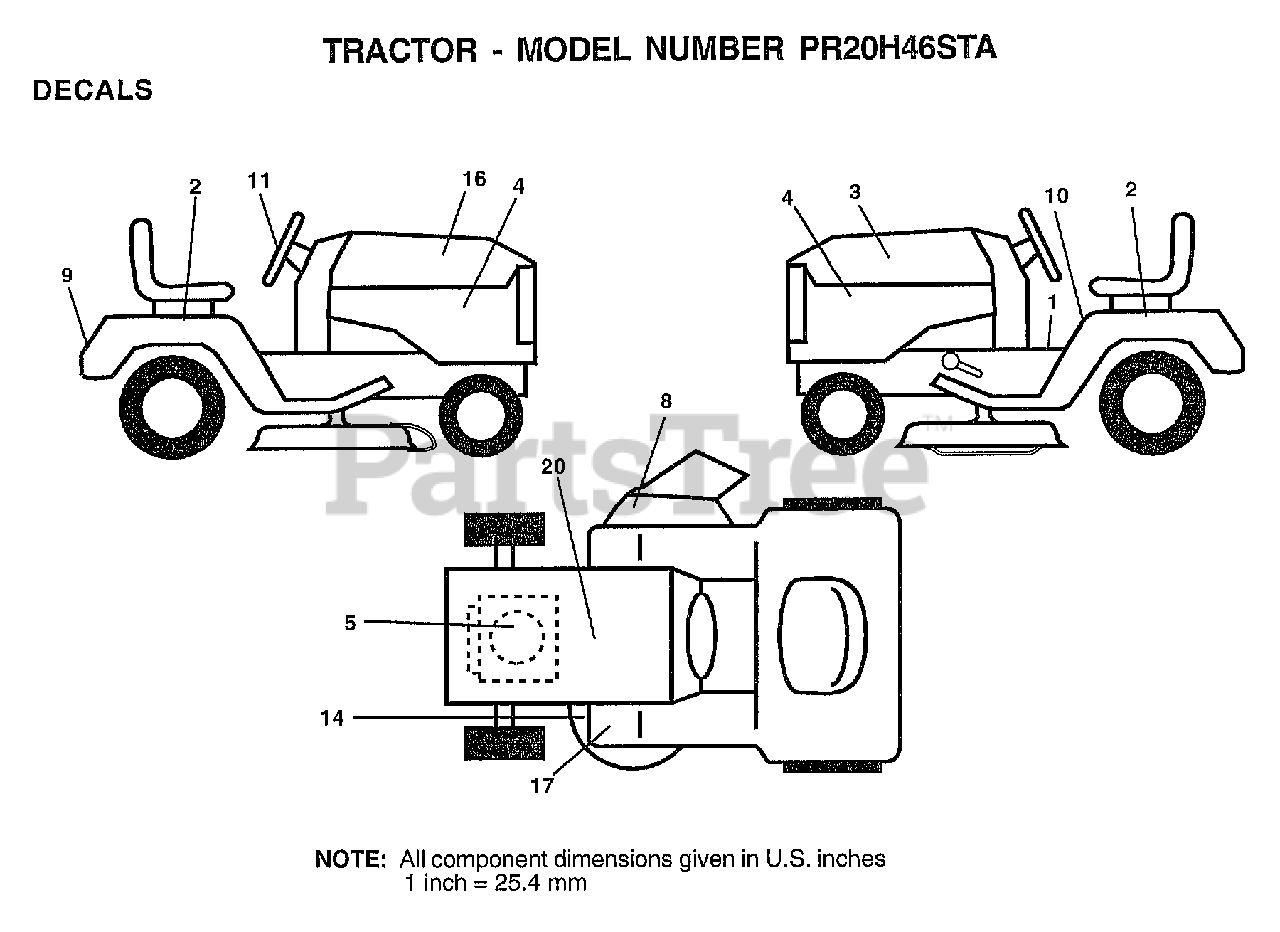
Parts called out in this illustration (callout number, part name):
1	DECAL SADDLE OPER
2	DECAL, FENDER
4	DECAL, SIDE PANEL
5	DECAL, ENGINE
8	DECAL
9	DECAL
10	DECAL.CAUT.ENG/FR
11	DECAL
17	DECAL T
20	DECAL.BATRY.3-3908
